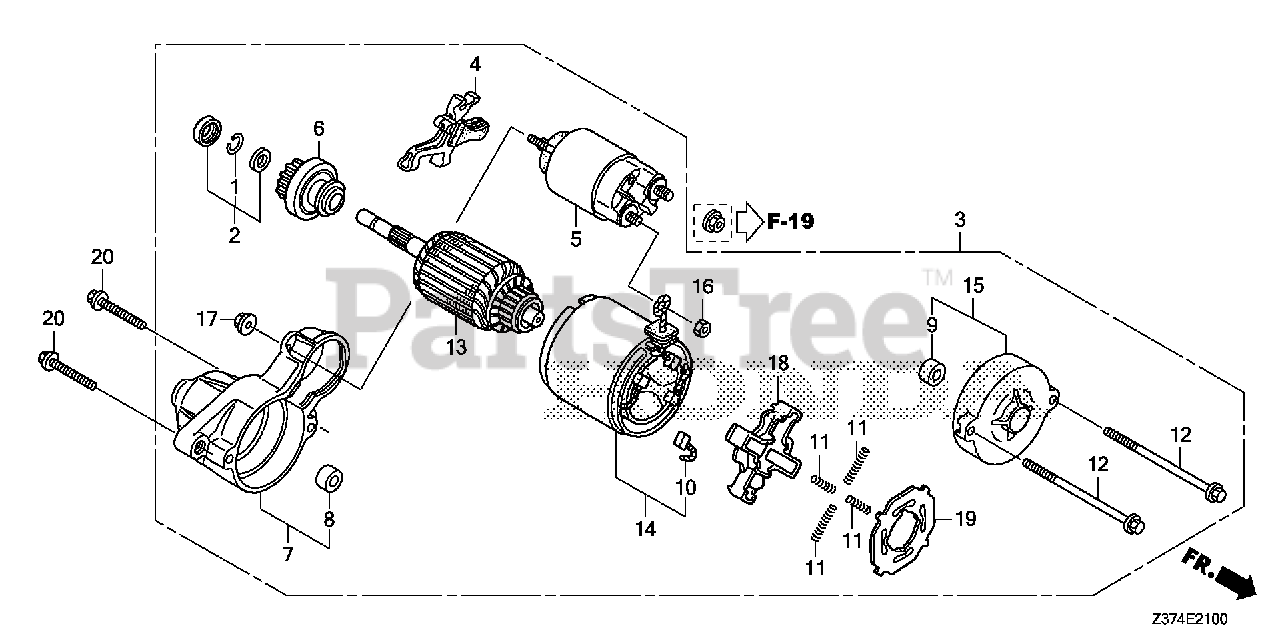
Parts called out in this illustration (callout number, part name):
1	RING, SNAP (DENSO)
2	COLLAR SET, CLUTCH STOP
3	STARTER MOTOR ASSY.
3	STARTER MOTOR ASSY. (DENSO)
4	LEVER, PINION DRIVE
4	LEVER, PINION DRIVE (NOT AVAILABLE)
5	SWITCH ASSY., MAGNET
6	CLUTCH, OVERRUNNING
7	HOUSING, DRIVE SIDE
9	BEARING B
10	BRUSH
11	SPRING, BRUSH
12	BOLT, THROUGH
13	ARMATURE
13	ARMATURE (NOT AVAILABLE)
15	FRAME, COMMUTATOR END
16	NUT, HEX. (8MM)
17	NUT, FLANGE (5MM)
17	NUT
18	HOLDER, BRUSH
19	INSULATOR, BRUSH HOLDER
20	BOLT, FLANGE (10X35)
